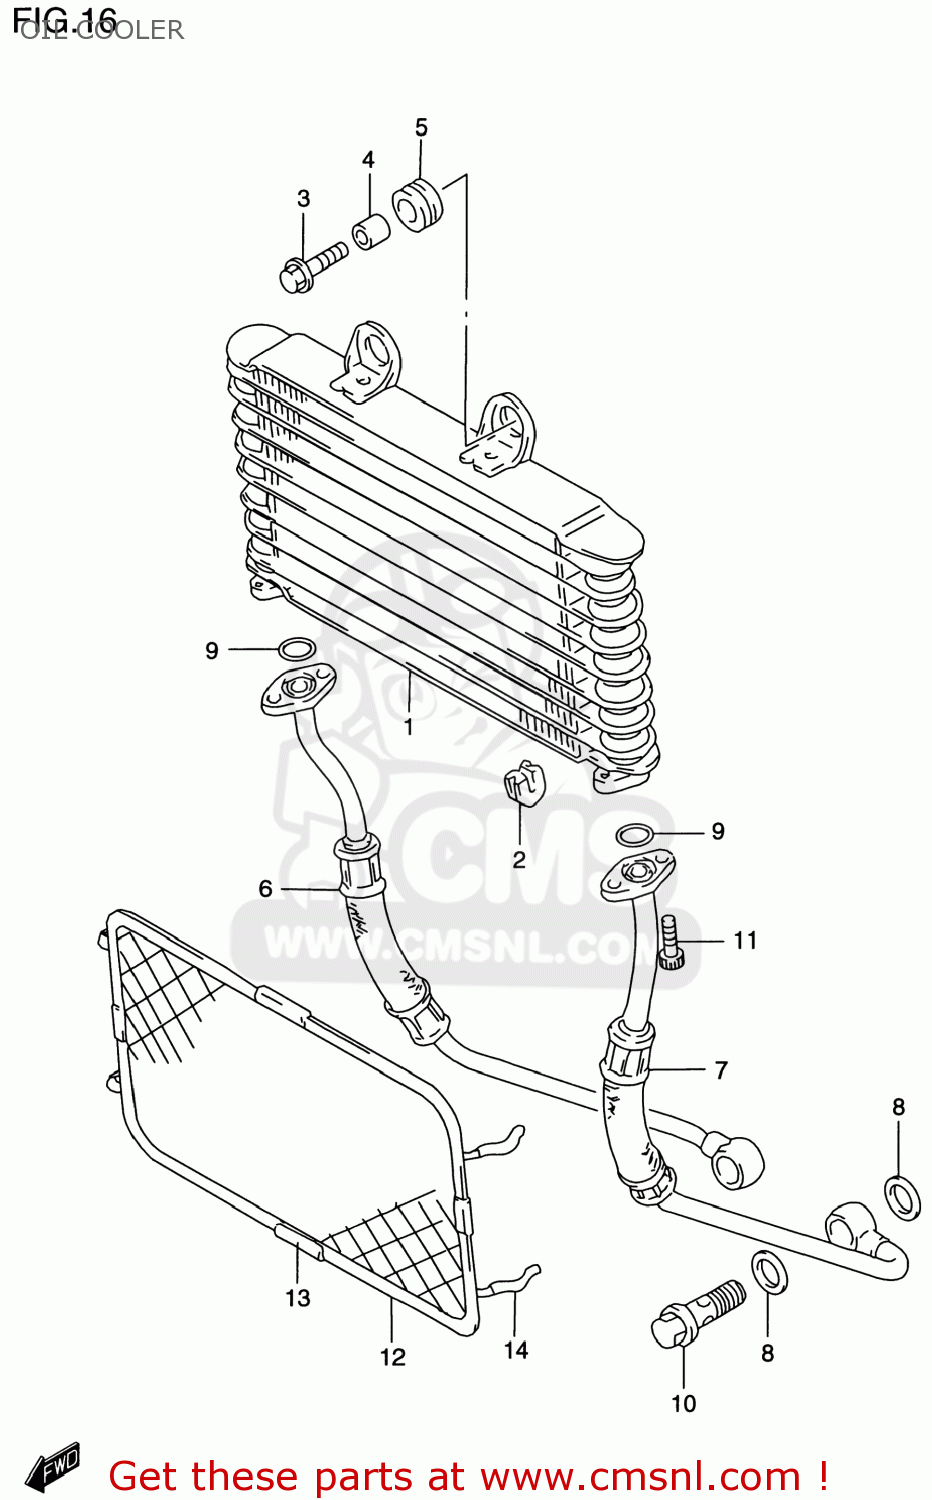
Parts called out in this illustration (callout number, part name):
1	COOLER ASSY,OIL
2	CUSHION,OIL COOLER NO.2
3	BOLT 6X20
4	SPACER(6.5X10X10)
5	CUSHION
6	HOSE,OIL COOLER,R
7	HOSE COMP,OIL COOLER,LEFT
8	GASKET(16X22X2) (NAS)
9	O RING(D:2.4,ID:12.3)
10	BOLT UNION
11	BOLT
12	GUARD,OIL COOLER
13	PROTECTOR,CTR
14	HOSE(3X5X600)
